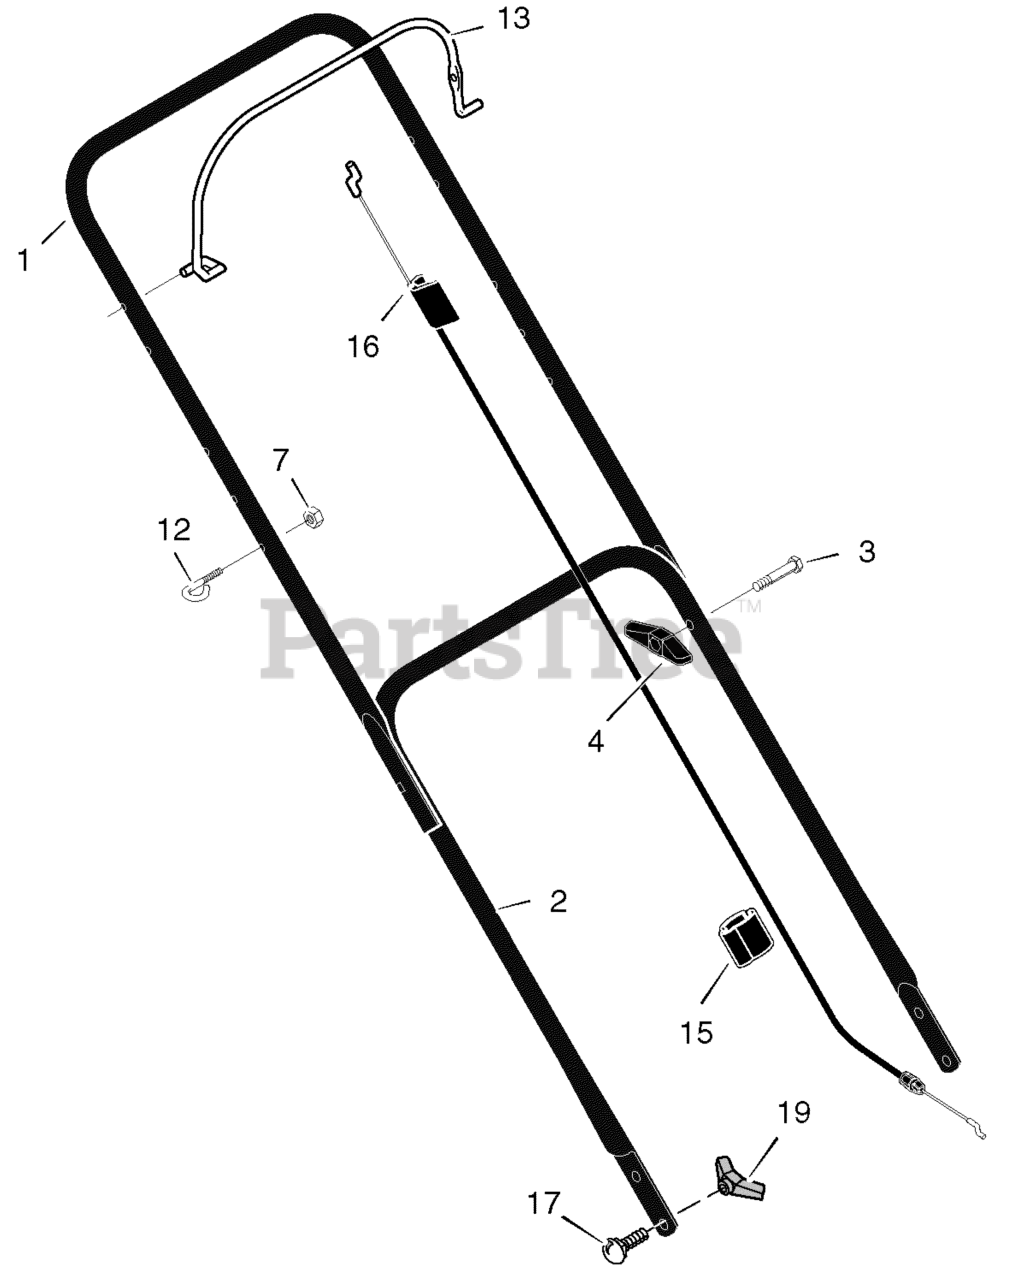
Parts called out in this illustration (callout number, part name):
1	Handle, Upper (Black)
2	Handle, Lower (Black)
4	Knob, Plastic
7	Locknut
12	Guide, Rope
13	Lever, Engine Stop
15	Clip, Cable
16	Engine Stop Cable
17	Bolt, Carriage
19	Knob, Plastic
